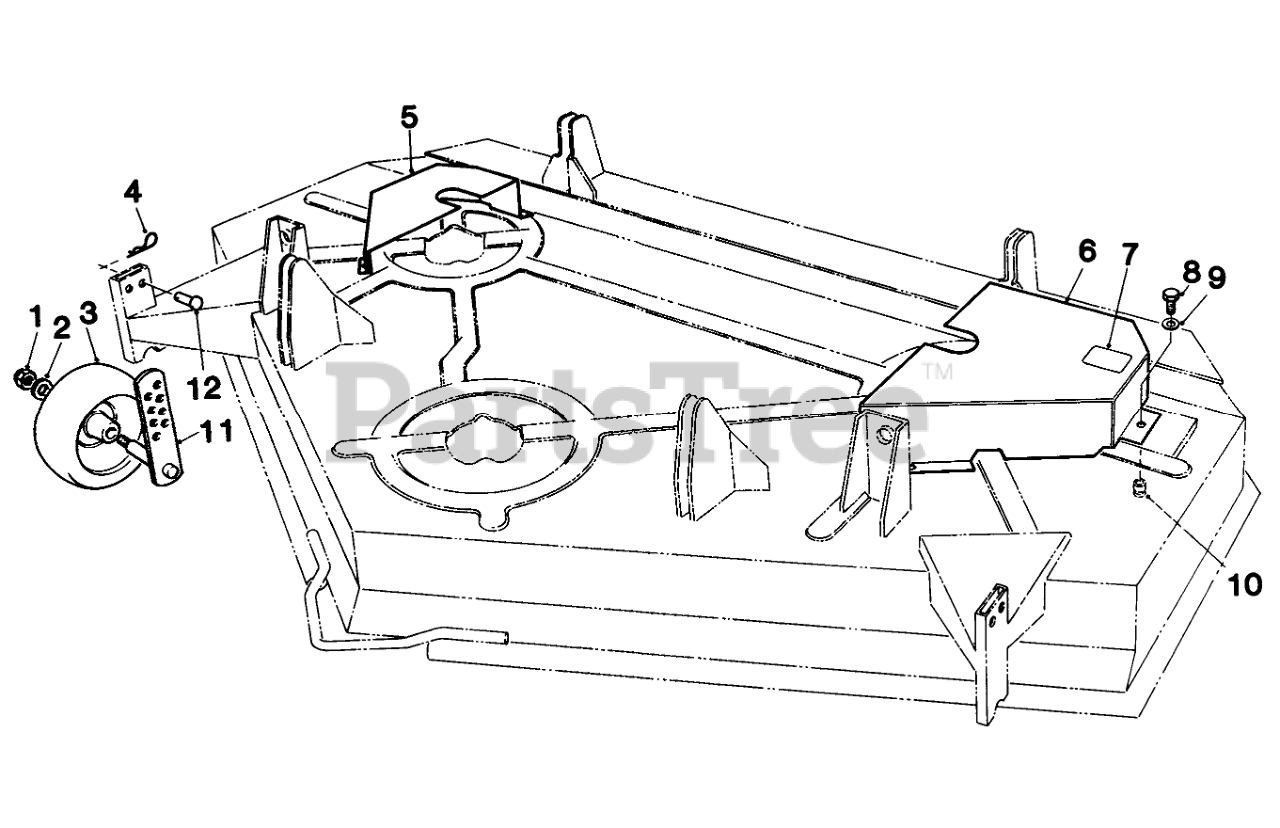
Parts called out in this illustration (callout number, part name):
1	NUT-LOCK, NI
2	WASHER-FLAT
3	WHEEL-GAGE
4	PIN-HAIR
5	R/H BELT COVER R/B
6	L/H BELT COVER R/B
7	DECAL-NO STEP
8	1/4-20 X 5/8 CAPSCREW
9	WASHER-FLAT
10	INSERT-THREADED
11	GAGE-WHEEL
12	PIN-CLEVIS
